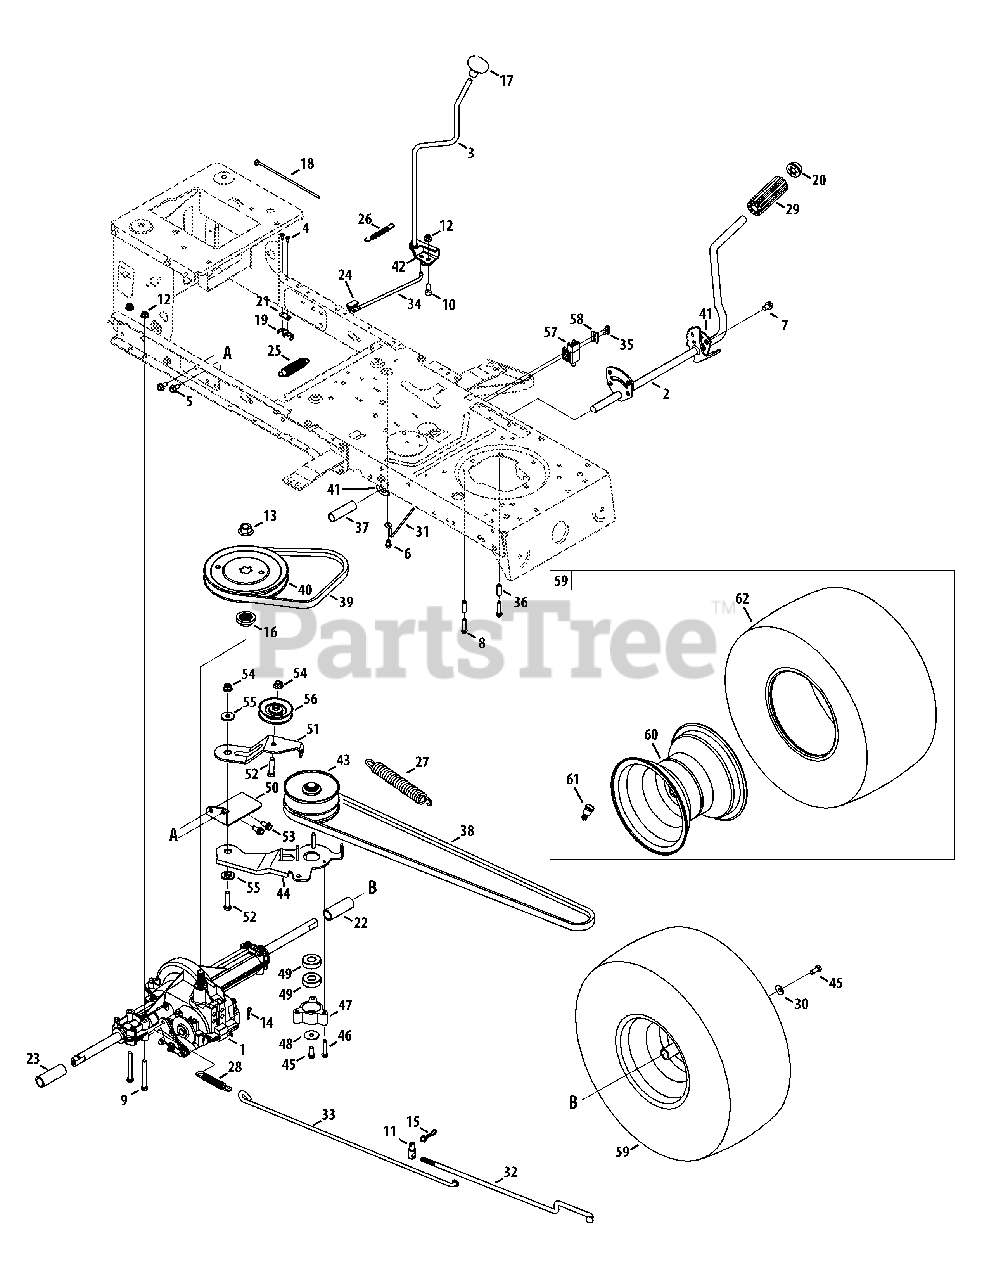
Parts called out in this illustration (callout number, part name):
1	Transmission Drive Assembly
2	Pedal Assembly
3	Shaft Lever Assembly
4	Screw, 8-18:0.500
5	Screw, 5/16-18 x .750
6	Screw, 1/4-20 x 0.500
7	Screw, 5/16-18 x 0.625
8	Screw, 1/4-20 x 1.250
9	Hex Screw, 5/16-18 x 2.75
10	Hex Screw, 5/16-18 x .75
11	Ferrule, 3/8-24 X .375 DIA.
12	Flangelock Nut, 5/16-18
13	Flange Nut, 9/16-18
14	Cotter Pin INT- .125 DIA
15	Bow-Tie Cotter Pin
16	Pulley Hub, 5/8 SPLINE
17	Shift Knob
18	Cable Tie
19	Short Spring Switch
20	Push Cap, 5/8
21	Plate Insulator Nut
22	Sleeve, .758 x .821 x 3.3125
23	Sleeve, .758 x .821 x 2.4375
24	Shift Bearing Plate
25	Spring Extension, .80 OD x 3.28 LG
26	Spring Extension, .38 OD x 3.25 LG
27	Spring Extension, .94 OD x 6.75 LG
28	Spring Extension, .59 OD x 4.00 LG
29	Foot Pad, 4.0 LONG
30	Bell Washer, .340 x .872 x .060
31	Belt Keeper Rod
32	Variable Speed Control Rod
33	Brake Rod
34	Shift Rod
35	Shoulder Screw, #10-32 x .500
36	Spacer, .260 x .375 x 1.030 LG
37	Spacer, .640 ID x .76 OD x 2.63
38	V Belt, 5L: 70.90 POLY
39	V Belt, 5L: 35.25 POLY
40	Trans. Pulley
41	Pedal Support Bracket
42	Shaft Adjust Bracket
43	Variable Speed Pulley Assembly
44	Bracket Assembly
45	Hex Screw, 5/16-24 x .750
46	Screw, 1/4-20 x 1.500
47	Bearing Cup
48	Flat Washer, .330 x 1.25 x .06:HT
49	Ball Bearing, 17 x 40 x 12
50	Transmission Bracket Assembly
51	Idler Bracket Assembly
52	Hex Screw, 3/8-16 x 1.75
53	Screw, 5/16-18 x 0.750
54	Flange Lock Nut, 3/8-16
55	Shoulder Spacer, .625 ID x .169
56	Idler Pulley
57	Switch Interlock
58	Plate Switch
60	Rim Assembly
61	Valve Stem
